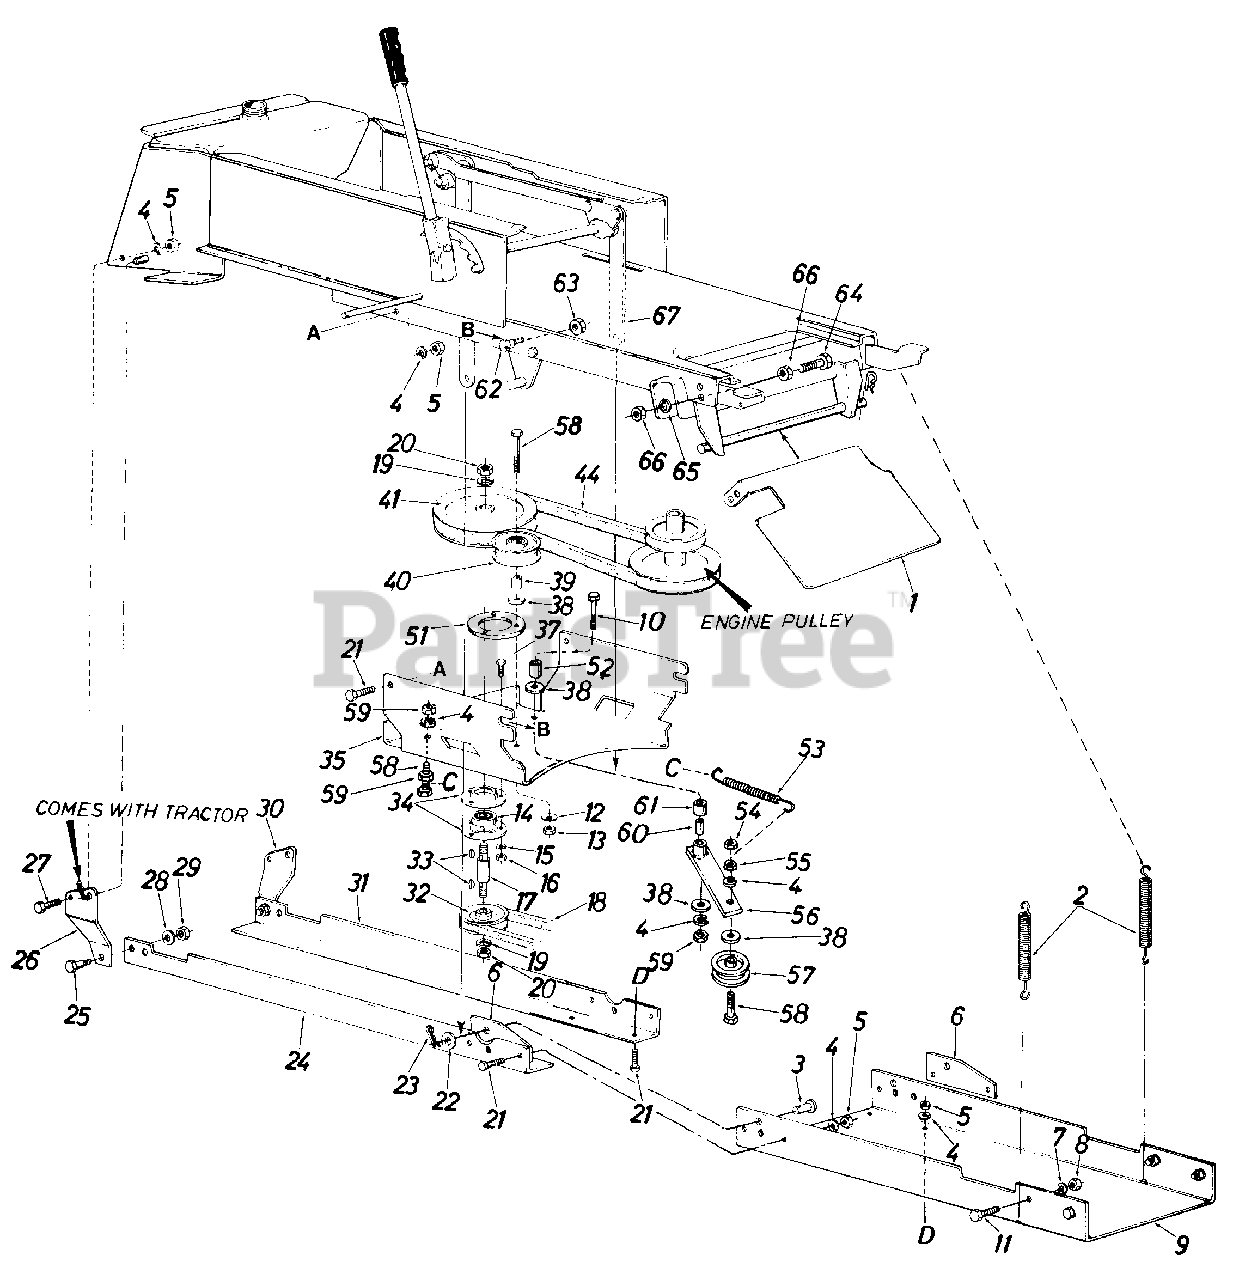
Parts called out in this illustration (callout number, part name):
1	Guide Bracket
2	Helper Spring
3	Clevis Pin
4	L.-Wash. 3/8" I.D.
5	Hex L.-Nut 3/8-24 Thd.
6	Attaching Plate
7	L.-Wash. 1/2" I.D.
8	Hex L.-Nut 1/2-20 Thd.
9	Front Support Channel
10	Hex Bolt 3/8-16 x 3.75" Lg.
11	Hex Bolt 1/2-20 x 1.25" Lg.
12	L-Wash. 3/8" I.D
13	Hex Jam \IU 3/8-16 Thd.
14	Ball Bearing
15	L.-Wash. 5/16" I.D.
16	Hex nut 5/16-18 Thd.
17	Spindle
18	"V'-Belt
19	L.-Wash. 5/8" I.D.
20	Hsx Jam Nut 5/8-11 Thd.
21	Hex Bolt 3/8-24 x 1.00" Lg.
22	Flat Washer
23	Internal Cotter Pin
28	Fl.-Wash. 44" I.D. x 1.38" O.D. x .130
29	Hex L.-Nut 7/16-24 Thd.
30	Rear Hanger Brkt. - L.H.
33	#6 Hi-Pro Key 3/16 x 5/8" Dia.
34	Bearing Housing
35	Supporting Bracket
37	Hex Sems Bolt 5/16-18 x 1.00" Lg.
38	Fl.-Wash. .38" I.D. x 1.00" O.D. x .135
39	Spacer.38" I.D. x .62" O.D.
40	Fl.-Idler Pulley
41	Upper Drive Pulley
44	"V'- Belt
53	Extension Spring .54" O.D. x 4.75" Lg.
54	Hex Cent. L.-Nut 3/8-16 Thd.
55	Hex Jam Nut 3/8-16 Thd.
56	Idler Arm Ass'y.
57	Idler Pulley
58	Hex Bolt 3/8-16 x 2.25" Lg.
59	Hex Jam Nut 3/8-16 Thd.
60	Spacer .377" I.D. x .60" O.D. x .830" Lg.
61	Spacer .380" I.D. x .630" O.D. x 565" Lg.
62	Shoulder Bolt .498 Dia. x .340
63	Hex Cent. L.-Nut 3/8-16 Thd.
64	Hex Bolt 1/4-28 x 1.50" Lg.
65	L.-Wash. 1/4" I.D.
66	Hex Nut 1/4-28 Thd.
